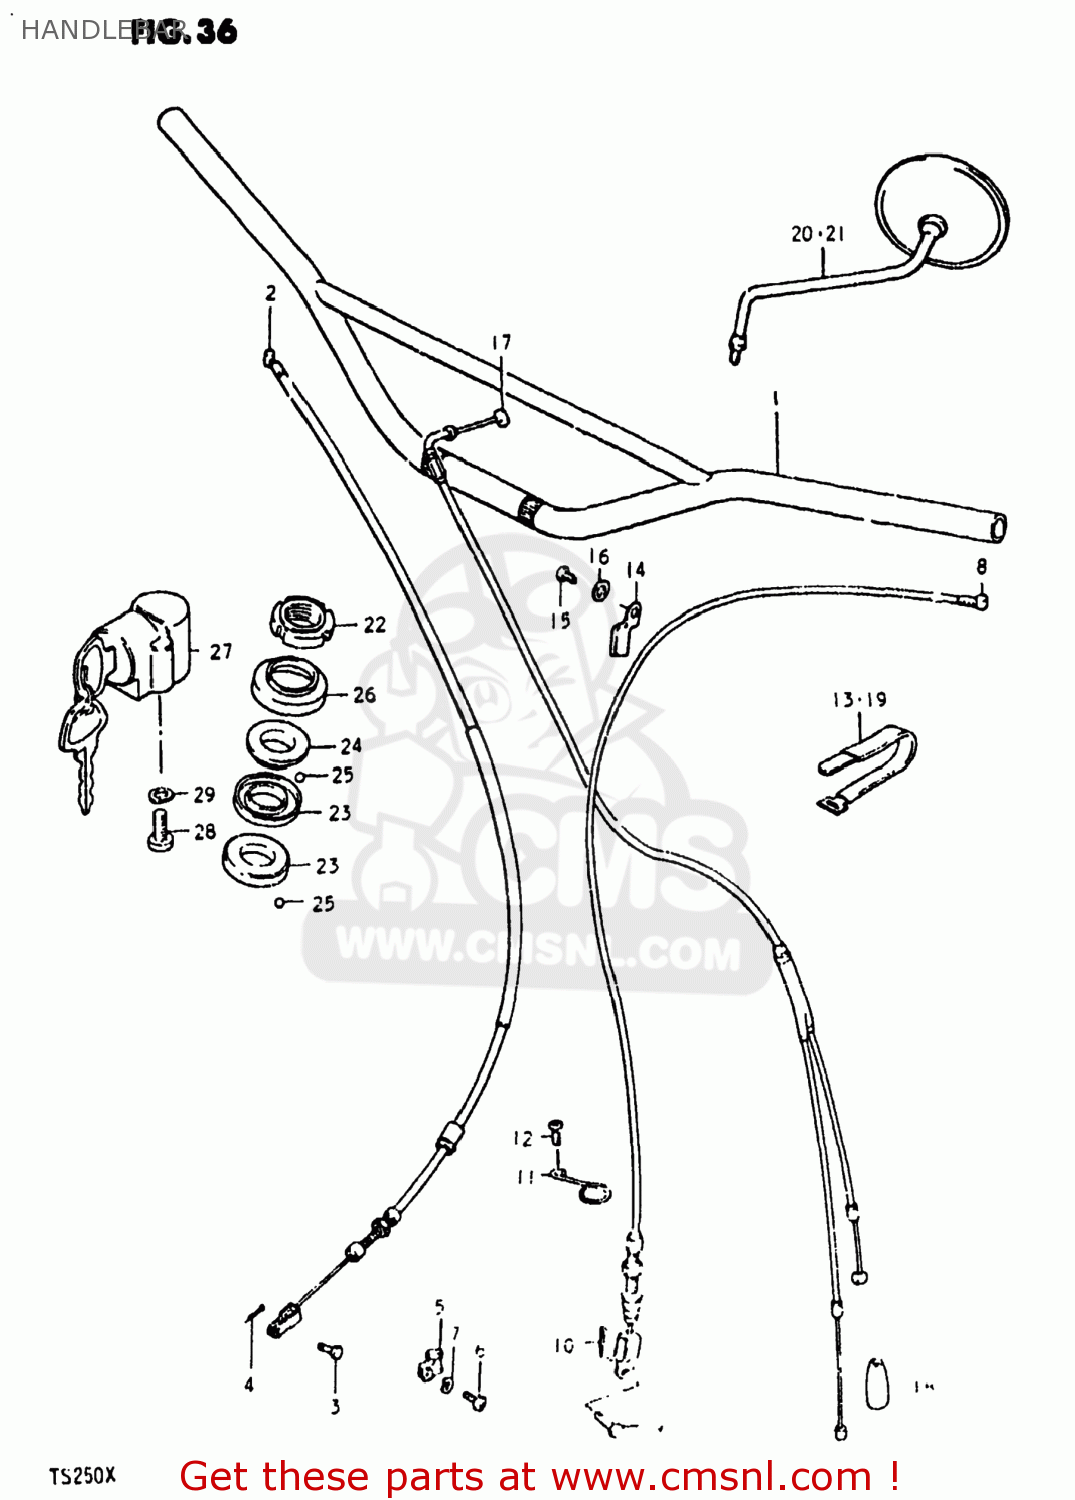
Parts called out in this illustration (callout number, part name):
1	HANDLEBAR
2	CABLE ASSY,FR BRAKE
3	PIN(L:17.5)
4	PIN
5	GUIDE,CABLE
6	SCREW
7	LOCK WASHER
8	CABLE ASSY,CLUTCH
9	PIN(L:15)
10	PIN
11	CLIP
12	SCREW
13	CLAMP
14	CLAMP
15	SCREW 6X12
16	WASHER
17	CABLE ASSEMBLY,THROTTLE
18	SEAL,DUST(7X18X30)
19	CLAMP
20	MIRROR ASSEMBLY,RIGHT
21	MIRROR ASSEMBLY,LEFT
22	NUT,STEERING STEM(25X44X10)
23	LACE,STEERING INNER LWR
24	LACE,STEERING OUTER UPR
25	BALL
26	DUST SEAL,STEERING UPR
27	LOCK ASSEMBLY,STEERING
28	SCREW
29	LOCK WASHER
